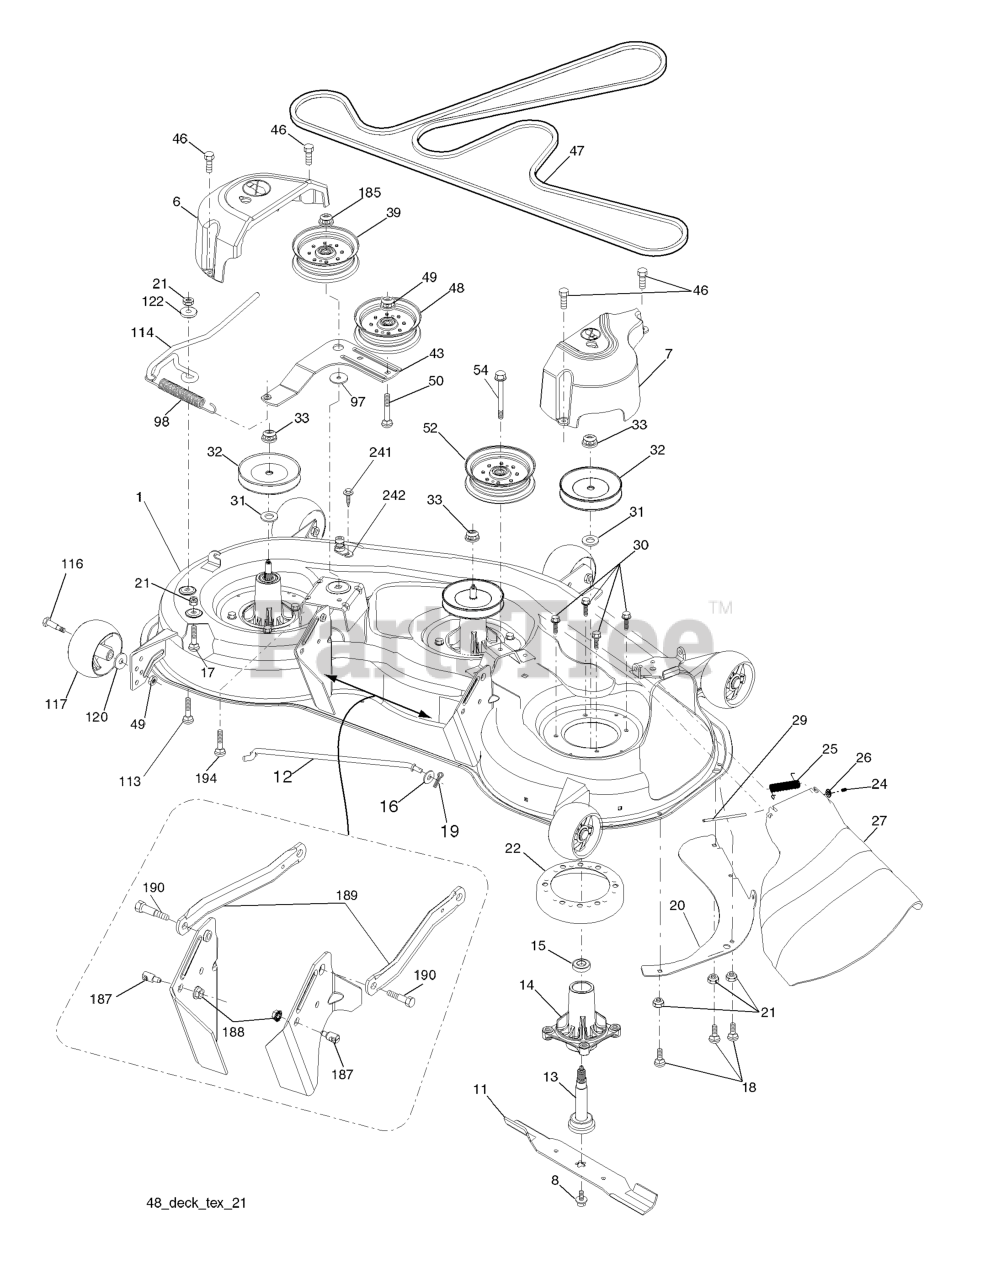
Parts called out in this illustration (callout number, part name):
1	DECK.WLDMT.W/TUBES.48"MS422
6	COVER.MANDREL.LH.48"(2 2)
7	COVER.MANDREL.RH.48"
8	BOLT 7/16 ASM BLADE
11	48" HI-LIFT BLADE
12	ROD.ANTI.SWAY.48/54"K4
13	SHAFT ASM MANDREL
14	RP.HOUSING.MANDREL.4PT.
16	WASHER
17	BOLT.CARR.5/16-18X5/8.SHORT
18	BOLT
19	PIN.COTTER.5/16.BOW TI
20	BAFFLE, VORTEX MWR
21	LOCKNUT
22	STRIPPER.MANDREL.ROUND.BLACK
24	CAP-SLEEVE LT
25	SPRING, TORSION
26	NUT PUSH M
27	DEFLECTOR SUBS TO 532 180655
29	ROD.HINGE
30	SCREW, WASHER HEAD
31	WASHER.SPACER.MANDREL
32	PULLEY MANDREL
33	NUT.FLANGE.LOCK.TOP
39	RB PULLEY.IDLER.4.50/HUB SPEC
43	ARM.IDLER
46	SCREW.1/4-20X5/8
47	BELT.DRIVE.DECK
48	PULLEY.IDLER.48"PRIMARY
49	NUT LOCK FLG 3/8-16 UNC
50	SCREW TT 3/8-16X2-1/4 UNC
52	PULLEY.IDLER.2006
54	BOLT.3/8-16X1.50
98	SPRING, DECK DRIVE
113	BOLT CRT
114	ROD.TENSION.RELIEF.TEX (2 2)
116	BOLT.SHOULDER.3/8-16X3-5/8.
117	RP WHEEL. GUAGE RALLY
120	WASHER
122	BUSHING.RELIEF.TENSION
185	NUT.LOCK.FLANGE.7/16
187	STUD.FASTNER.W/ANTI-ROTATE
188	NUT LOCK HEX FLANGE 5/16-18
189	ARM.SUSPENSION.MOWER
190	BOLT.SHOULDER
194	BOLT.CARR.SQNK.7/16
241	SCREW.TT.#10-32X.5.3/8.FLANGE
242	PORT.WASHOUT
242	RP.MANDREL ASM. SERVICE
242	Coupling, Quick Connect
242	DECK.ASM SVC.48".5GWB.ORANGE
